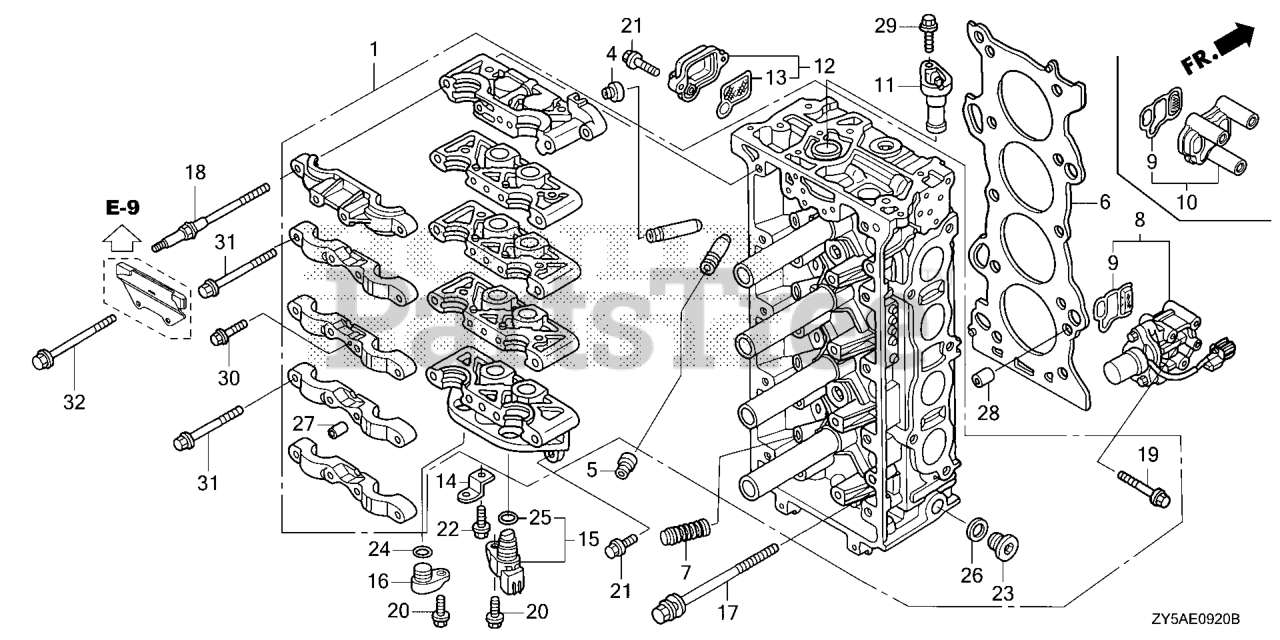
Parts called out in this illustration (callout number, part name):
1	CYLINDER HEAD KIT *NH8* (DARK GRAY)
2	GUIDE, VALVE (OVER SIZE)
3	GUIDE, EX. VALVE (OVER SIZE)
4	SEAL A, VALVE STEM (NOK)
5	SEAL B, VALVE STEM (NOK)
6	GASKET, CYLINDER HEAD
7	MOTION, LOST
8	VALVE ASSY., SPOOL *NH8* (DARK GRAY)
9	FILTER ASSY., SPOOL VALVE
11	PLUG, VTC HOLE
12	STRAINER ASSY., VTC *NH8* (DARK GRAY)
13	FILTER ASSY., VTC
14	BRACKET F, CLIP
15	SENSOR ASSY., TDC
16	PLUG, TDC HOLE
17	BOLT-WASHER (11X155)
18	BOLT A, HEAD COVER
19	BOLT, FLANGE (6X52)
20	BOLT, FLANGE (6X16)
21	BOLT, FLANGE (6X20)
22	BOLT, FLANGE (6X14)
23	BOLT, SEALING (20MM)
24	O-RING (15X1.9)
25	O-RING (15X1.9)
26	WASHER, DRAIN PLUG (20MM)
27	PIN A, DOWEL (10X16)
28	PIN A, DOWEL (14X20)
29	BOLT, FLANGE (6X20)
30	BOLT, FLANGE (6X32)
31	BOLT, FLANGE (8X90)
32	BOLT, FLANGE (8X110)
